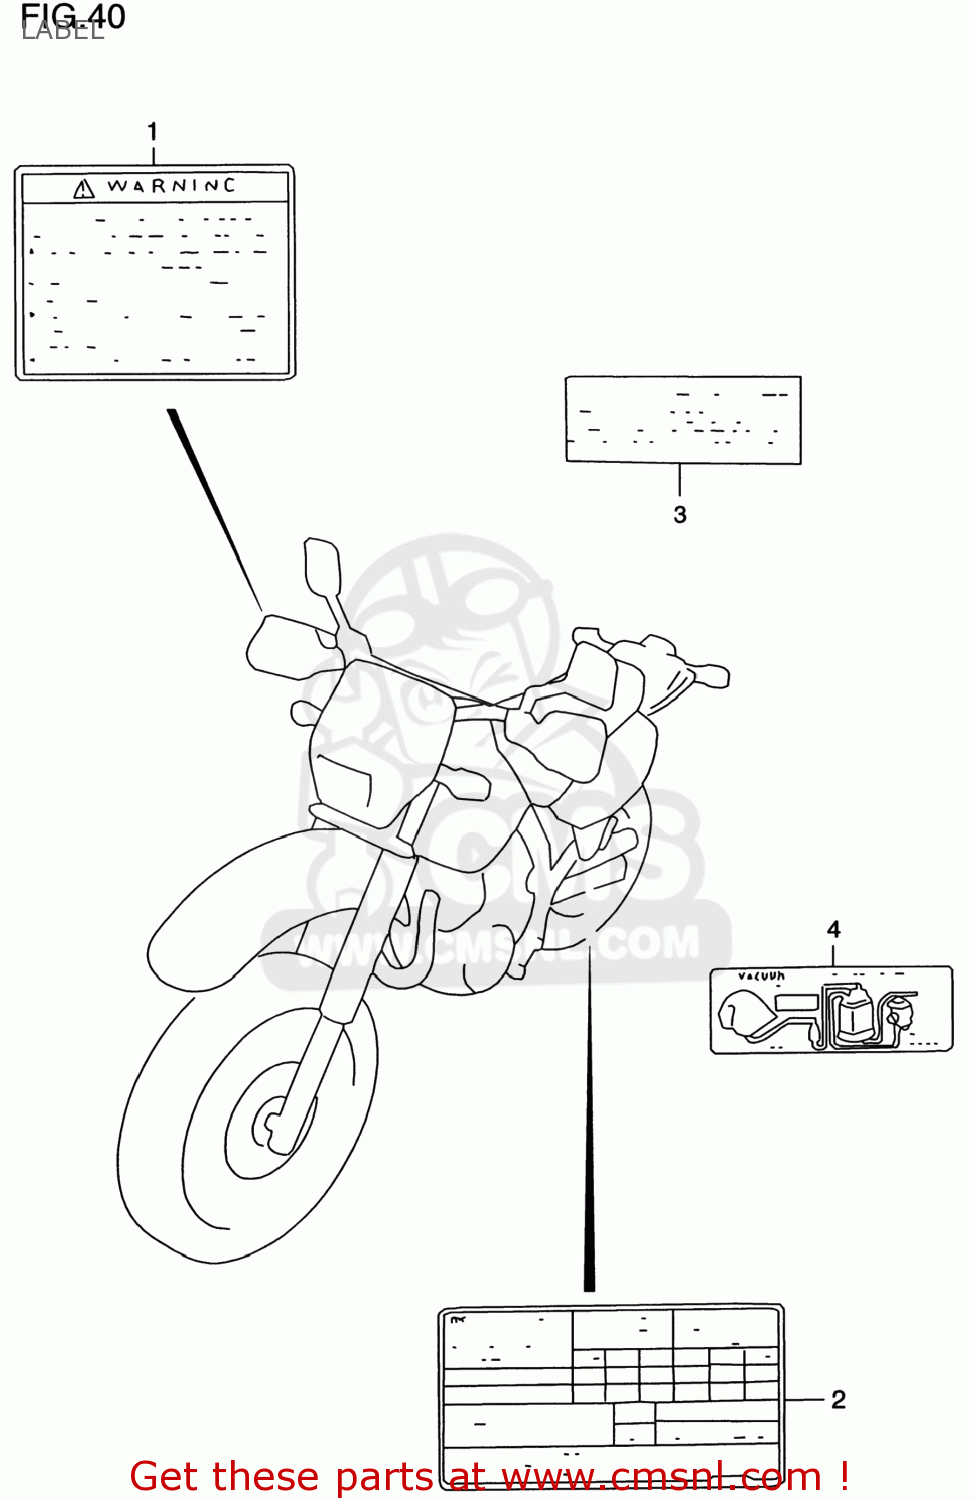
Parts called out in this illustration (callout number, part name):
1	LABEL,GENERAL WARNING
2	LABEL,TIRE AIR PRESSURE
3	LABEL (MANUAL NOTICE)
4	LABEL,PIPING DIAG
5	MANUAL, OWNER'S
6	LABEL,STARTING CAUTION
